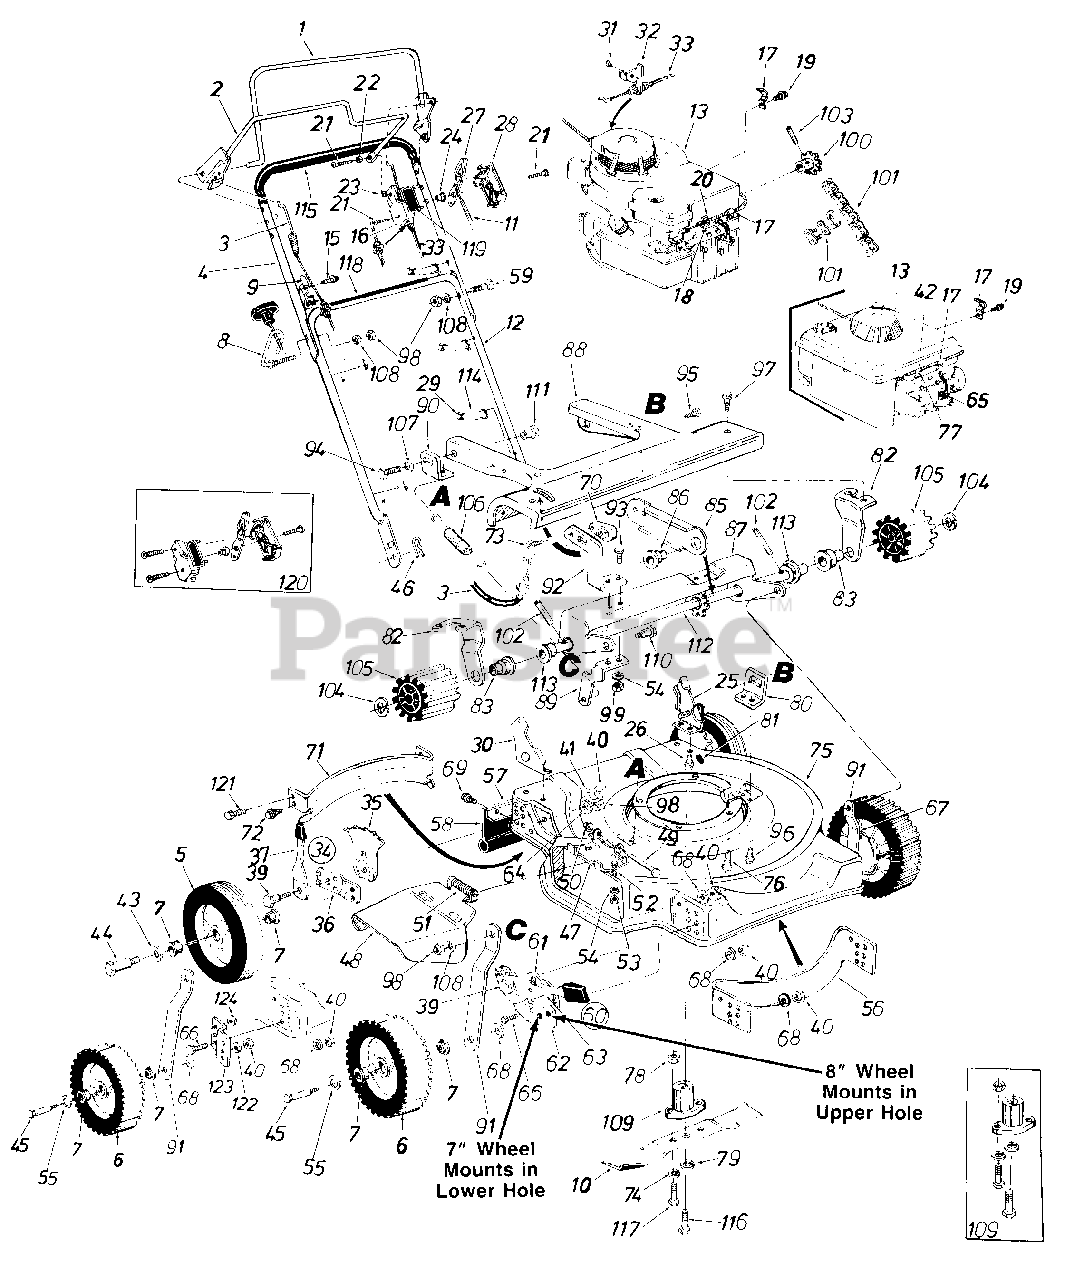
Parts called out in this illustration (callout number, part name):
1	Control Handle Ass'y.
2	Control Handle
3	Control Cable w/Spring-47" Lg. (Green)
4	Upper Handle
5	Rear Wheel Ass'y. Comp.
6	Rear Wheel-Smooth Tread (8 x 1.75)
7	Flange Brg. 1/2" I.D.
8	Rope Guide Bolt
9	Cable Mtg. Brkt.
10	22" Blade
11	Throttle Wire 58" Lg. (Green)
12	Lower Handle
13	Engine
15	Hex AB-Tap Scr. 5/16-18 x 314
16	Clutch Panel Half
17	Casing Clamp
18	Hex AB-Tap Scr. #8 x .50 Lg.
19	Hex B-Tap Scr. #10 x .38 Lg.
20	Casing Clamp
21	Truss Hd. B-Tap Scr. #12 x 1.5" Lg.
22	Spacer .23 I.D. x .30 O.D.
23	Spr. Wash. .206 I.D. x .448 O.D.
24	Control Disc Pin
25	Handle Mtg. Brkt. Ass'y.
26	Hex B-Tap Scr. 5/16-18 x .50"
27	Throttle Control Lever
28	Control Panel Half
29	Cable Anchor
30	Handle Mtg. Brkt. Ass'y.
31	Pop Rivet .156 Dia. x .316 Lg.
32	Cable Bracket
33	Control Cable-43" Lg. (Yellow)
34	Rear Height Adjustment Ass'y.-R.H.
35	Index Plate
36	Wheel Pivot Bar
37	Spring Lever w/Knob
39	Shld. Bolt .500" Dia. x .430" Lg.
40	Hex Nut 3/8-16 Thd.*
41	Bell-Wash. .39 I.D. x 1.38 O.D. x .062
42	Casing Clamp
43	Bell-Wash. .40 I.D. x .88 O.D. x .06
44	Rear Axle Bolt
45	Front Axle Bolt
46	Int. Cot. Pin 5/16 Dia.
47	Adapter Plate
48	Chute Deflector Ass'y.
49	Pivot Pin
50	Cap Speed Nut 1/4 Rod
51	Torsion Spring
52	Hex Bolt 1/4-20 x .50 Lg.
53	Hex Nut 1/4-20 Thd.*
54	L-Wash. 1/4" I.D.*
55	Fl-Wash. .531 I.D. x .93 O.D. x .090
56	Front Baffle
57	Retaining Strip-14" Lg.
58	Rear Flap
59	Carr. Bolt-5/16-18 x 1.75" Lg.
60	Front Height Adjustment Ass'y.-R.H.
61	Index Plate
62	Pivot Bar
63	Spring Lever w/Knob
64	Bell-Wash. .345 I.D. x .88 O.D.
65	Spark Plug Insulator
66	Hex Bolt 3/8-16 x .75
67	Front Height Adjustment Ass'y.-L.H.
68	Bell-Wash. .400 I.D. x .88 O.D. x .060
69	Hex Tap Scr. 1/4 x .62 Lg.
70	Barrel Cable Hold Down-L.H.
71	Rear Baffle
72	Truss Mach. Scr #10 x .50
73	Hex B-Ta Scr. #10 x .44" Lg.
74	L-Wash. 5/16" I.D.*
75	22" Deck Ass'y.
76	Hex TT-Tap Scr. 3/8-16 x 1.0" Lg.
77	Hex 'B'-Tap Scr. #10 x .62" Lg.
78	Hex Nut 5/16-24
79	L-Wash. 3/8" I.D.-H.D.
80	Pivot Bracket
82	Axle Bracket
83	Fl. Ball Brg. 1/2" I.D.
85	Brg. Support
86	Fl. Ball Brg. 1/2" I.D.
87	Drive Engagement Cam
88	Front Pinion-Pivot Cover
89	Spring Mtg. Brkt.
90	Pivot Bracket
91	Link-5.30 x .88"
92	Engage. Arm-R.H.
93	Carr. Bolt 1/4-20 x .62 Lg.
94	Hex Bolt 3/8-16 x .50 Lg.
95	Hex B-Tap Scr. 1/4 x .38 Lg.
96	Hex AB-Tap Scr. 1/4 x .62 Lg.
97	Hex AB-Tap Scr. 1/4 x .62 Lg.
98	Hex Nut 5/16-18 Thd.*
99	Hex Nut 1/4-20 Thd.*
100	10 Tooth Sprocket Ass'y.
101	#48 Chain 1/2" Pitch-50 Links
102	Spring Pin 3/16 Dia. x 1.25 Lg.
103	Spring Pin 3/16 Dia. x 1.00 Lg.
104	E-Ring
105	13 Tooth Drive Pinion
106	Ext Spring-.50 O.D. x 4.25 Lg.
107	Bell-Wash. .400 I.D. x .88 O.D. x .060
108	L-Wash. 5/16" I.D.
109	Blade Adapter Kit
110	Shld. Bolt .437 Dia. x .162 Lg.
111	Shld. Nut .625 Dia. x .165 Lg.
112	Pinion Shaft w/7 Tooth Sprocket
113	Fl. Ball Bearing 1/3" I.D.
114	Cable Tie
116	Hex Bolt 3/8-24 x 2.25" Lg.
117	Hex Bolt 5/16-24 x 1.0" Lg.
118	Instruction Label
119	Control Label
120	Kit-Control Housing Comp.
121	Hex Bolt 5/16-18 x .75" Lg.
122	L-Wash. 3/8" I.D.
123	Wheel Brkt.
124	Fl-Wash. .385" I.D. x .62" O.D.
